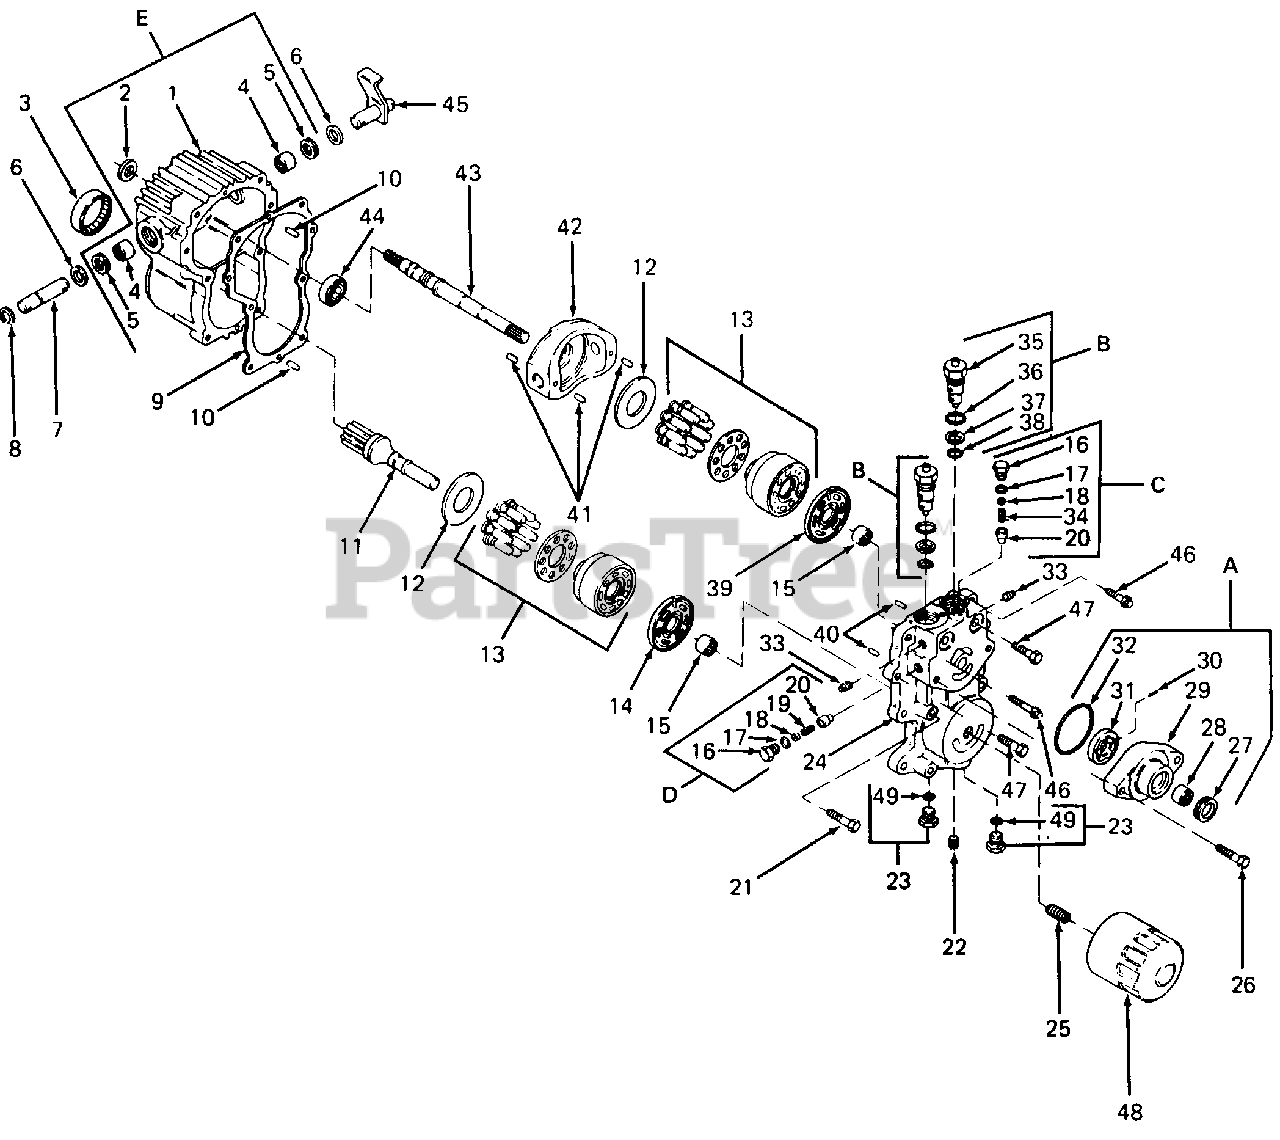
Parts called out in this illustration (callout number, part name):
1	Housing, Transmission
2	Seal, Lip
3	Bearing, Roller
4	Bearing, Needle
5	Seal, Lip
7	Shaft, Trunnion
8	Ring, Retaining
9	Gasket
10	Pin
11	Shaft, Motor
12	Plate, Thrust
13	Block, Cylinder
14	Plate, Valve
15	Bearing, Roller
16	Plug
17	O-Ring
18	Kit, Shim Pack
19	Spring, Center Relief Valve
20	Cone, Relief Valve
24	Center Section
27	Seal, Lip
28	Bearing, Needle
29	Charge Pump Housing
31	Gerotor
34	Spring, Implement Relief
35	Valve
37	Ring, Back-up
39	Plate, Valve
43	Shaft, Pump
45	Shaft Assembly, Trunnion
46	Screw, 12 Point
48	Oil Filter
A	Kit, Charge Pump
B	Valve Assembly
C	Kit, Relief Valve
D	Kit, Relief Valve
E	Housing Assembly
